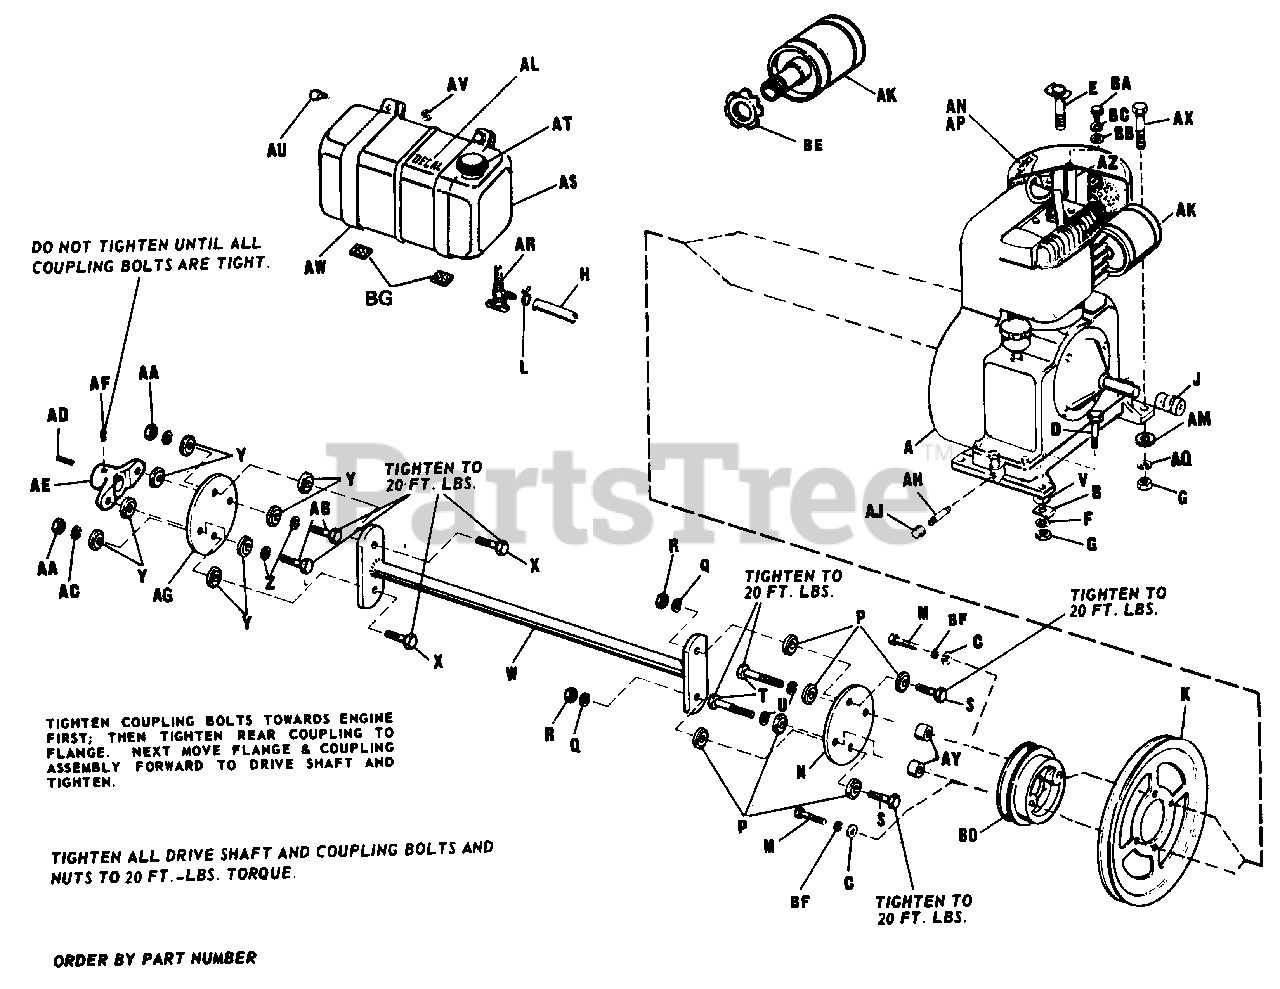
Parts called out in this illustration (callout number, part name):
A	ENGINE, Briggs & Stratton
B	Stop Axle
C	Lock Washer, 3/8"
D	Hex. Cap Screws, 3/8"-16 x 1-3/4" lg.
E	Screw Assembly, Engine, L.H. Rear
F	Lock Washer, 3/8"
G	Full Hex. Nut, 3/8"-16
H	Fuel Hose (Flexible)
J	Crankshaft Extension Guard
K	Engine Pulley
L	Hose Clamp (FOR SERVICE ONLY)
M	Hex. Cap Screw, 5/16"-18 x 2
P	Special Washer
Q	Lock Washer, 3/8"
R	Full Hex. Nut, 3/8"-16
S	Hex. Cap Screw, 3/8"-16 x 1-1/4" lg.
T	Hex Capscrew, 3/8-16 x 2-1/2" lg.
U	Lock Washer, 3/8"
V	Plain Washer, 3/8"
W	Drive Shaft Assembly
X	Hex. Cap Screw, 3/8"-16 x 1-1/4" lg.
Y	Special Washer
Z	Lock Washer, 3/8"
AA	Full Hex. Nut, 3/8"-16
AB	Hex. Cap Screw, 3/8"-16 x 1-1/4"
AC	Lock Washer, 3/8"
AE	Drive Shaft Flange
AF	Cup Point Socket Head Set Screw, 3/8"-24 x 5/8"
AH	Pipe Nipple, 3/8 x 1" lg.
AJ	Pipe Cap, 3/8"
AK	Exhaust Muffler
AL	Decal, Fuel Tank
AM	Plain Washer, 3/8"
AN	Film, Air Cleaner
AP	Film, Air Cleaner
AQ	Lock Washer, 3/8"
AR	Shut-Off Valve
AS	Fuel Tank
AT	Fuel Tank Cap
AU	Hex. Hd. Capscrew, 1/4"-20 x 1-3/4"
AV	Full Hex. Nut, 1/4"-20
AW	Tank Strap
AX	Hex. Hd. Capscrew, 3/8"-16 x 2" lg.
AZ	Air Cleaner Spacer
BA	Hex. Hd. Capscrew 1/4"-20 x 5/8"
BB	Plain Washer, 1/4"
BC	Lock Washer, 1/4"
BF	Lock Washer, 5/16"
